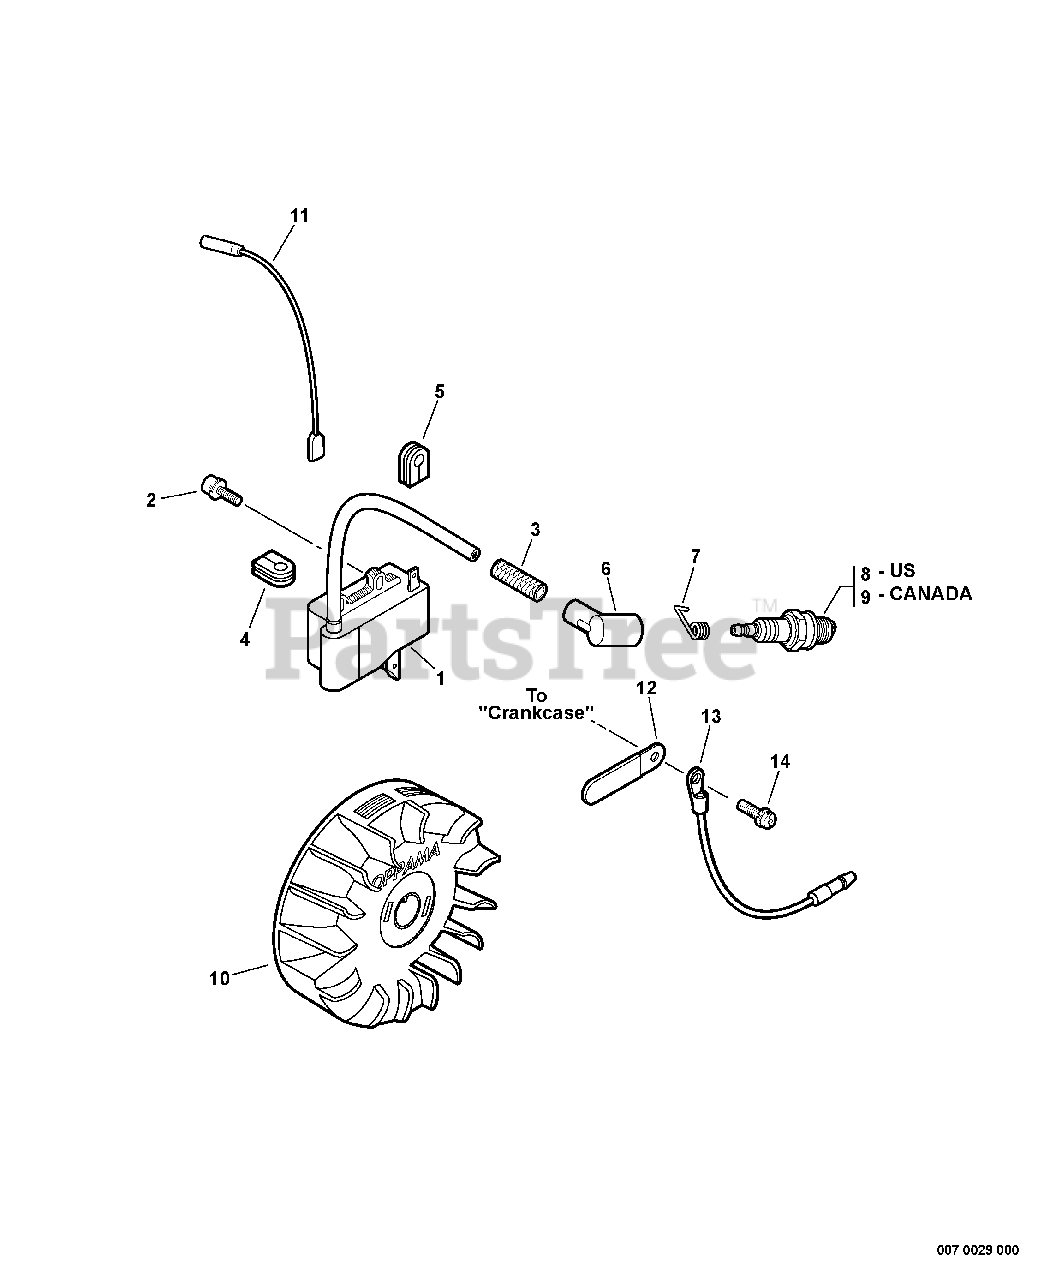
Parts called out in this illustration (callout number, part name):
1	COIL, IGNITION
2	BOLT 4×20
3	TUBE, INSULATOR
4	GROMMET
6	CAP, SPARK PLUG
7	TERMINAL, SPARK PLUG
8	SPARK PLUG - BPM8Y
9	SPARK PLUG - BPMR8Y
10	FLYWHEEL
11	LEAD - IGNITION
13	LEAD - GROUND
14	SCREW 5×10
